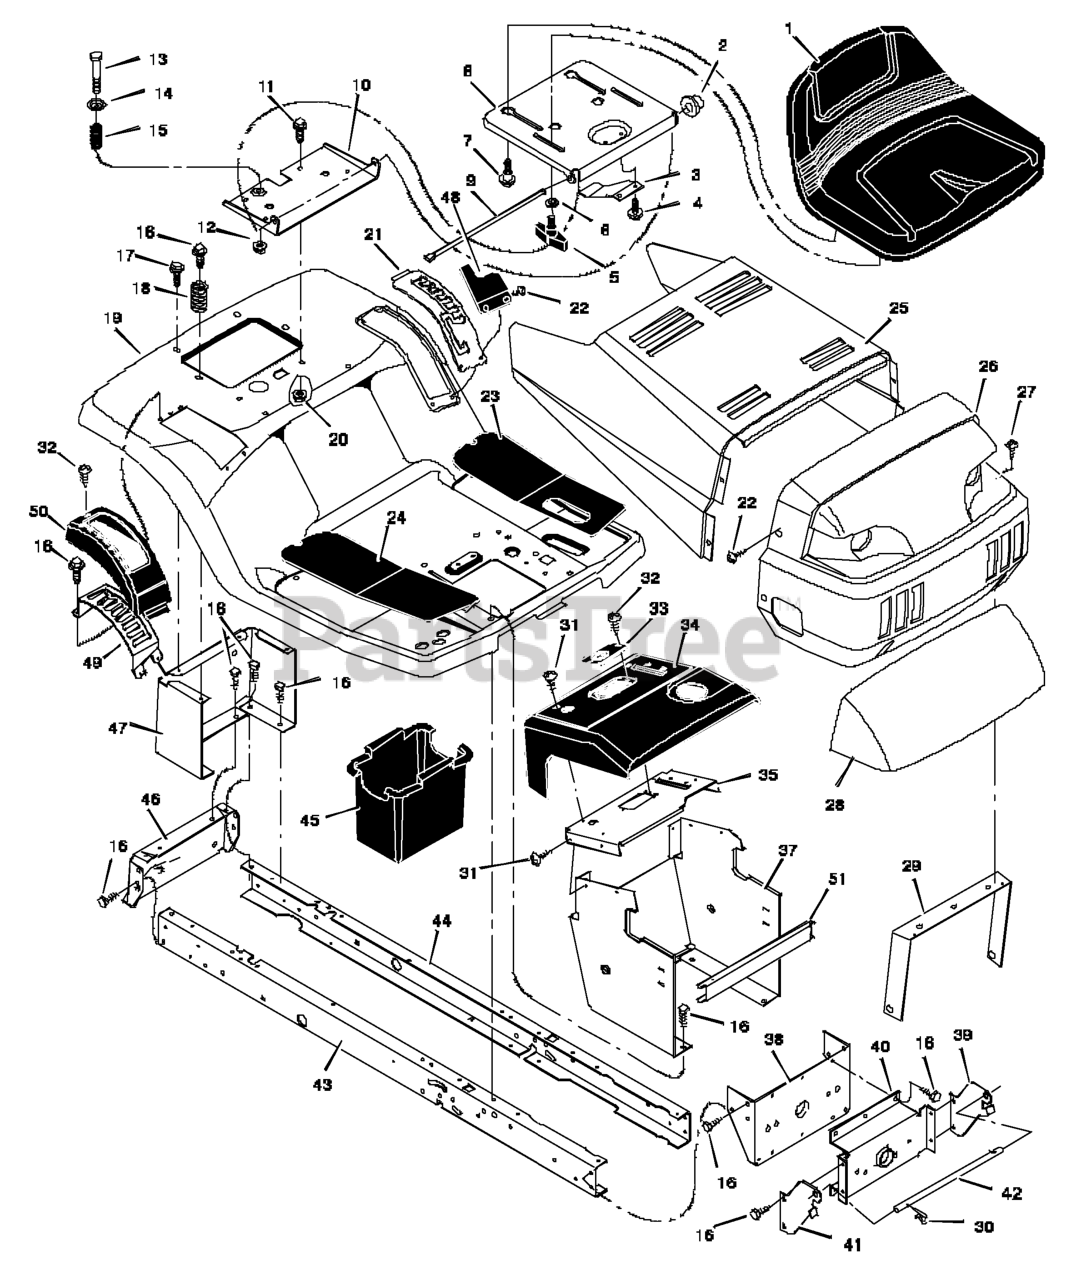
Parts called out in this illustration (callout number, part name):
2	Cap, Push On
5	Bolt, Wing
6	Washer
7	Bolt, Shoulder
8	Support, Seat
9	Rod, Pivot
10	Bracket, Pivot
11	Bolt
13	Bolt, Shoulder
15	Spring
19	Deck, Seat
20	Nut
21	Plate, Lift Index
23	Mat, Left
24	Mat, Right
26	Grille Assembly
29	Brace, Grille
30	Pin, Hair
31	Screw
33	Bearing, Steering
35	Plate, Dash
36	Panel, Access
37	Support, Dash
38	Bracket, Rear Hanger
39	Support, Left Grille
40	Axle, Hanger
41	Support, Right Grille
42	Rod, Pivot
43	Frame, Right
44	Frame, Left
45	Container, Battery
46	Plate, Hitch
47	Panel, Rear
48	Cover, Level Adjustment
49	Gate, Shift
50	Cover, Shift Gate
